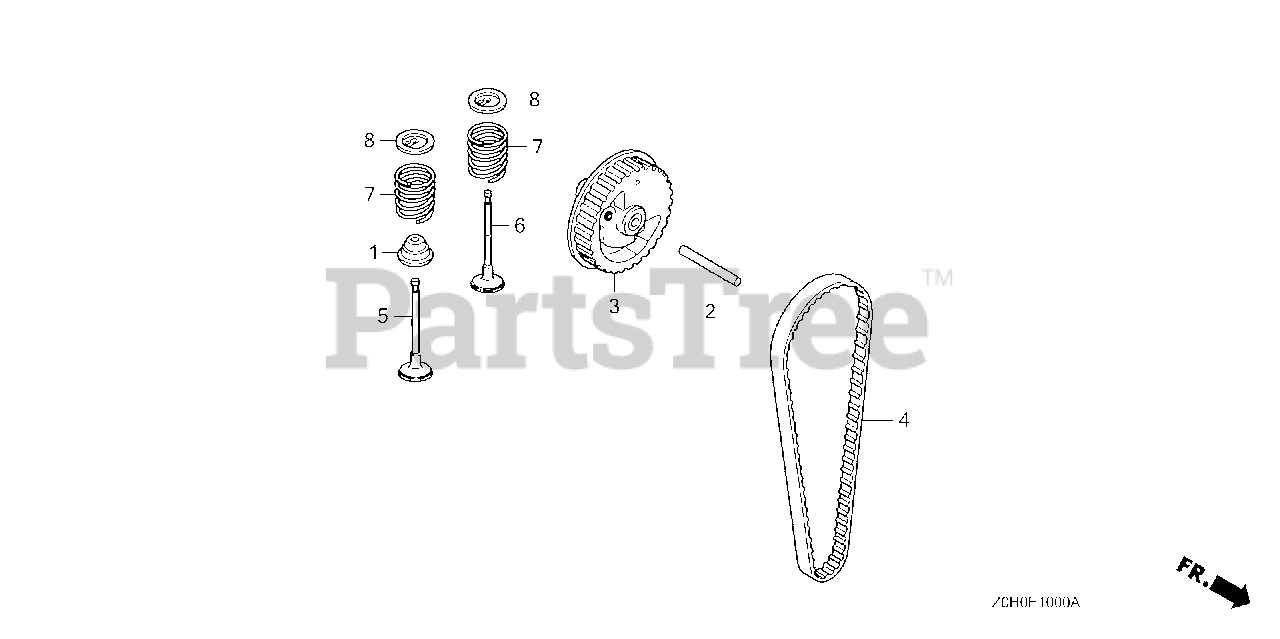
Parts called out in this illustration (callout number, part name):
1	SEAL, VALVE STEM
2	ROLLER (4X29.8)
3	PULLEY, CAMSHAFT
4	BELT, TIMING (71ZU5 G-310)
5	VALVE, IN.
6	VALVE, EX. (HE)
6	VALVE, EX. (EE)
7	SPRING, VALVE
8	RETAINER, VALVE SPRING
